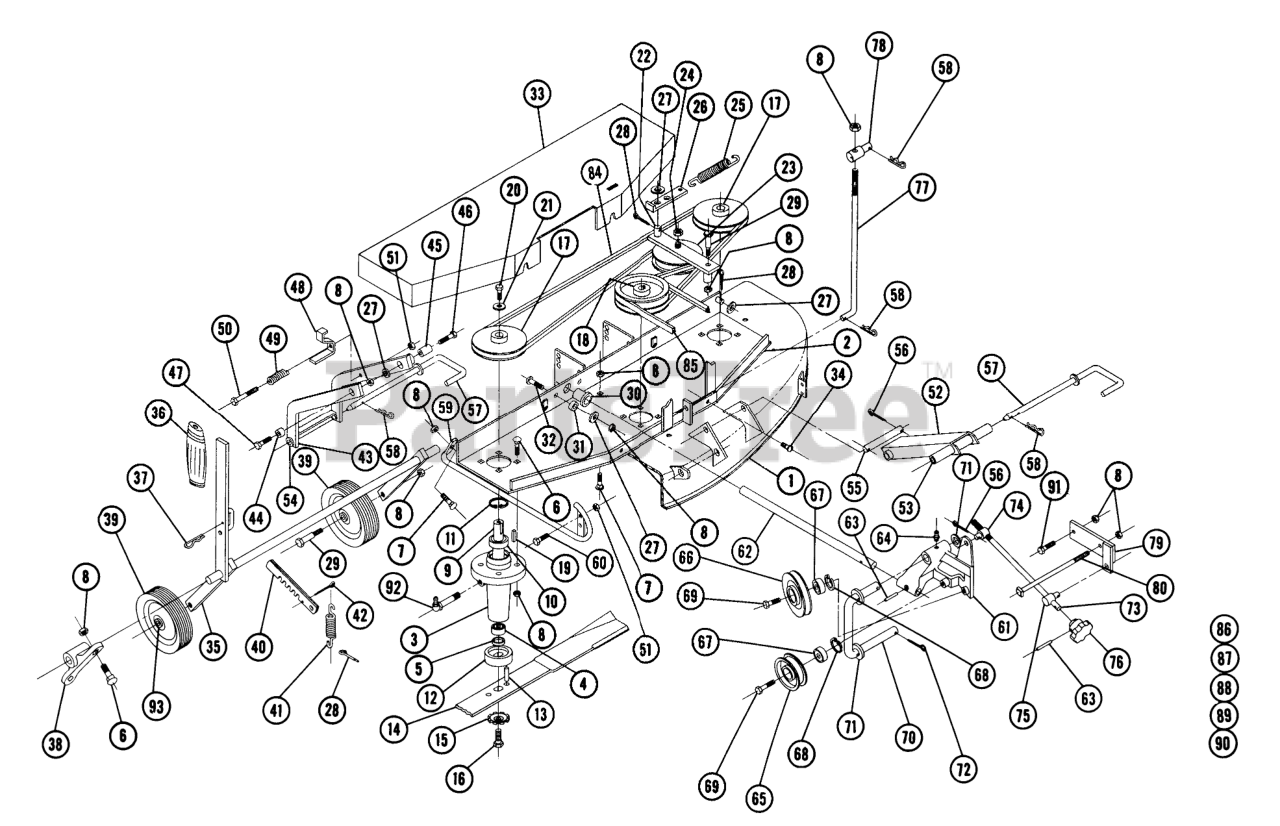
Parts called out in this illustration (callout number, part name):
1	Ass-y. Deck
2	Ass-y. Channel-Deck Support
3	Housing
4	NEEDLE BEARING
5	Seal
6	Bolt 3/8-16 x 1
7	Bolt-3/8-16 x 3/4
9	SPINDLE SHAFT
10	Ball
11	Snap-Ring 1 5/8 Bore
12	SPINDLE CUP
13	SPIROL ROLL PIN
14	Blade
15	WASHER
16	Bolt-Nylock 3/8-16 x 7/8
17	Pulley
18	Pulley-Double Groove
19	KEY-STRAIGHT
21	WASHER
22	Bolt-Shoulder
23	Pulley-Idler
24	Locknut-1/2-13
25	Spring
26	Plate Spring Adj.
27	Washer
28	Cotter Pin
29	BOLT-SHOULDER
30	Bushing
31	SPACER
32	Bolt-Truss HD. 3/8-16 x 7/8
33	Cover
34	H.H.C.S. 1/4-20 x 1/2
35	Ass-y. Gage Wheel Adj. Rod
36	Grip
37	Hairpin
38	Bearing-Cast Iron
39	Wheel
40	Ass-y. Arm-Gage Wheel
41	Spring
42	Cotter Pin 1/8 x 1/2
43	Ass-y Trip Lever
44	Spacer
45	Spacer
46	Bolt, 3/8 16 x 2
47	Bolt 3/8-16 x 1
48	latch-Lift
49	SPRING-COMPRESSION
50	Bolt-Hex 3/8-16 x 2
51	Nut-Nylok
52	Ass-y. Lift Link-Front
53	Bushing
54	FLANGED BUSHING
55	Pin-Front Link-Lower
56	Cotter Pin
57	Ass-y. Pin Lift Link
58	Hairpin
59	Washer
60	Bolt, 5/16-18 X 7/8
61	Bracket-Idler Mtg.
62	Rod-Leveling
63	PIN-ROLL
64	Zerk
65	Pulley Idler
66	PULLEY IDLER
67	BEARING
68	Snap Ring 1 3/8 Bore
69	Bolt 3/8-16 x 1 1/4 Nylok
70	Shaft-Idler Support
71	WASHER
72	Cotter Pin 5/32 x 1 1/4
73	Rod-Drive Adj.
74	Trunnion
75	Stud
76	Knob
77	Rod
78	LIFT STUD
79	Ass-y.-Belt Adj. Bracket
80	Bolt-Hex. 3/8-16 x 8 1/2
81	Housing
82	OIL SEAL
83	Bearing-Needle
84	V-BELT
85	V BELT
86	Wrench 1/8 Hex Allen
87	Decal
88	DECAL
89	Decal
90	Decal Belt Installation
92	Fitting-Grease
93	Bushing-Wheel
